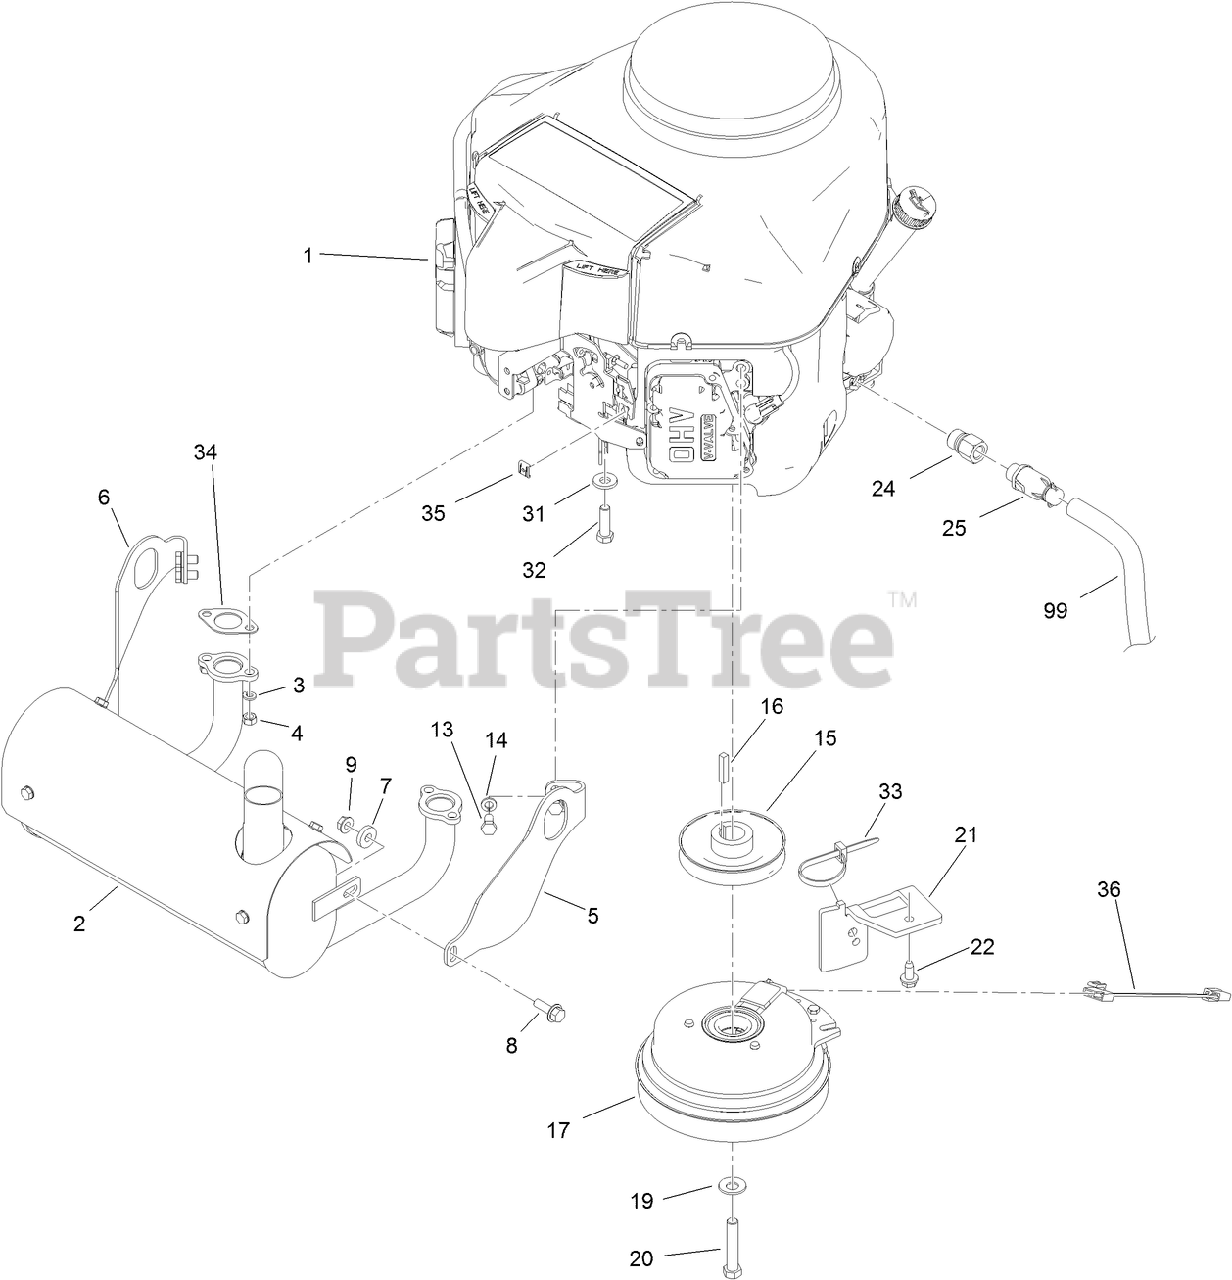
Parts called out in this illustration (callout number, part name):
2	MUFFLER
3	WASHER-LOCK
5	BRACKET-MUFFLER MOUNT, LH
6	BRACKET-MUFFLER MOUNT, RH
7	SPACER
8	SCREW-HHF
9	NUT-HF
13	SCREW-HH
14	WASHER-LOCK
15	PULLEY
17	CLUTCH
19	WASHER-SPRING
20	SCREW-HH
21	BRACKET-ANCHOR, CLUTCH
22	SCREW-HWHTF
24	Adapter
25	VALVE-DRAIN, OIL
31	WASHER-BELLEVILLE
32	SCREW-HH
33	TIE-CABLE
34	GASKET-EXHAUST
35	CLAMP-CABLE
36	HARNESS-WIRE
99	HOSE-DRAIN, OIL
